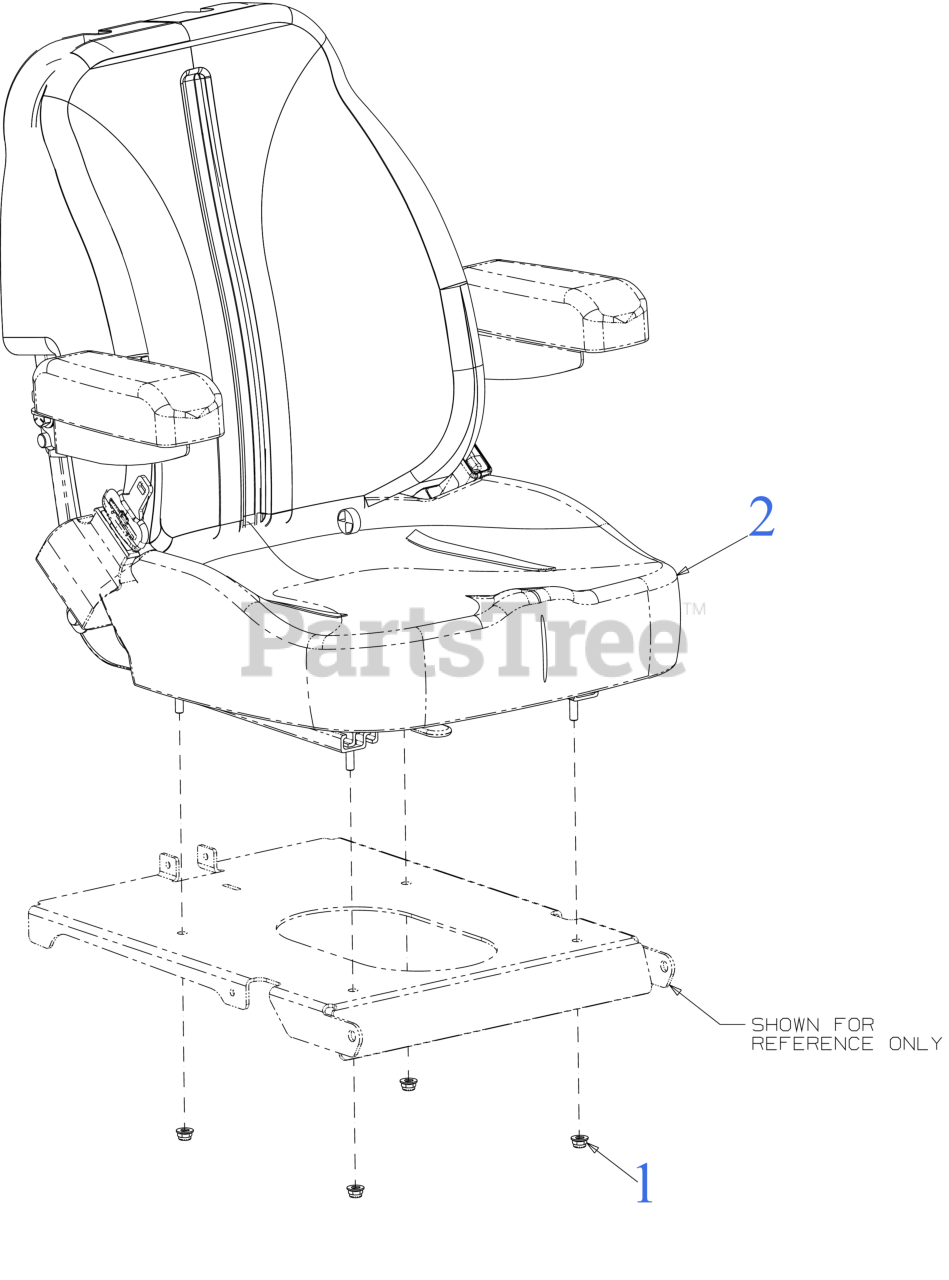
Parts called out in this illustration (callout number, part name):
1	FLANGE LOCK NUT 5/16-18
2	SEAT (CUB SLIDE/BELT/ARM REST)
2	SEAT SWITCH N/C,N/C
